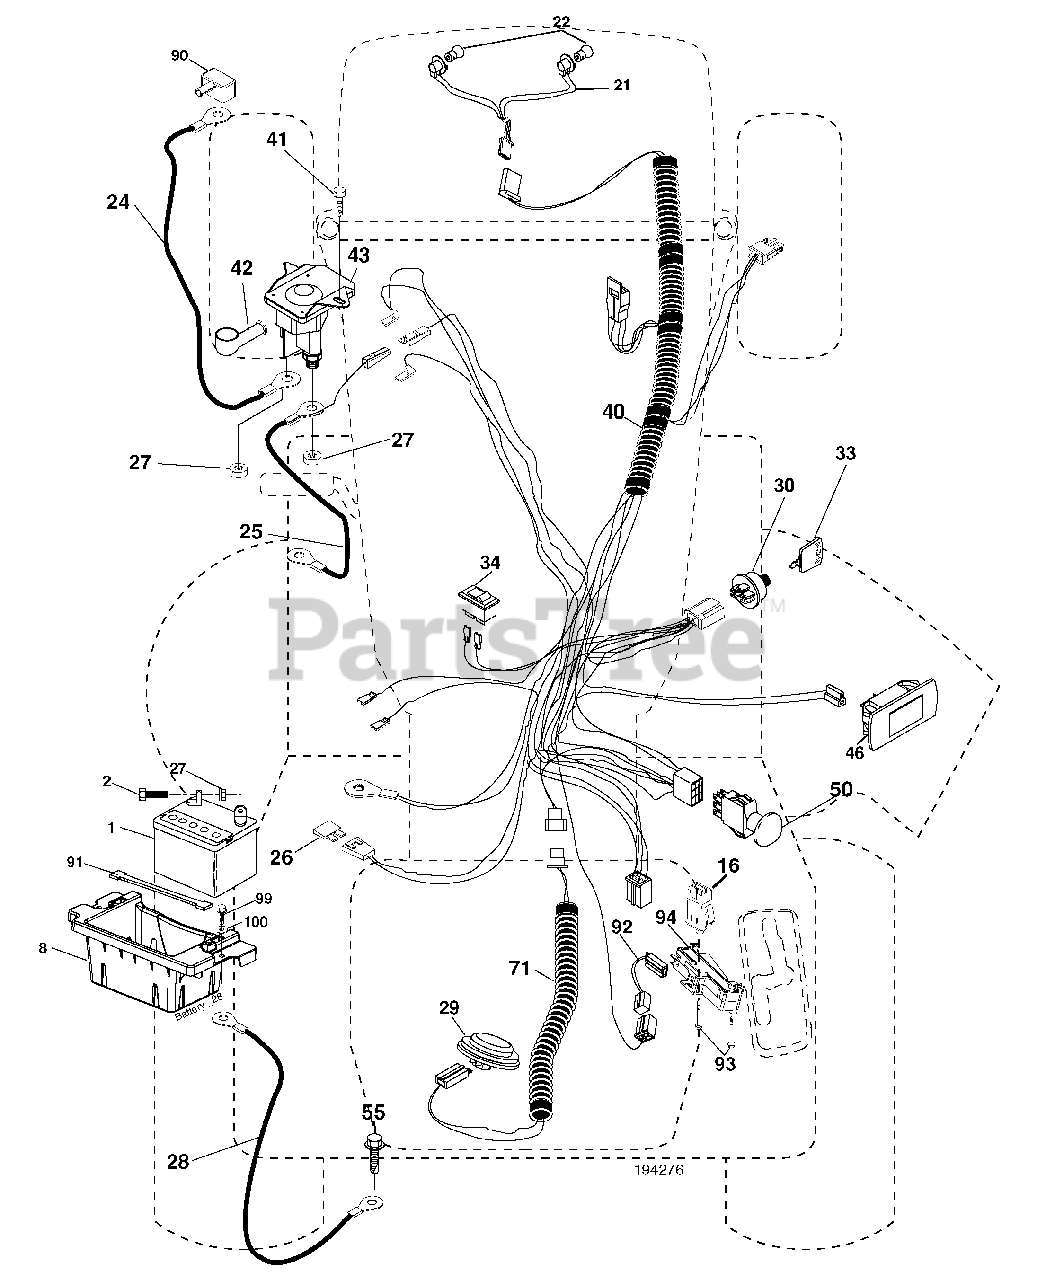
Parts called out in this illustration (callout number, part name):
1	Battery
2	Bolt Hex Head 1/4-20 x 3/4
8	Box Battery
16	Switch Interlock Push-In
21	Harness Socket Light W/4152J
22	Bulb Light
24	Cable Battery
25	Cable Starter
26	Fuse
27	Nut Keps Hex 1/4-20 unc
28	Cable, Ground
29	Switch, Seat
30	Switch, Ign
33	Key, Ignition
34	Switch Light / Reset
40	Harness Ign.
41	Screw Thd Cut 1/4-20 x 1/2
42	Cover, Terminal
43	Solenoid
46	Gauge Hourmeter
50	Switch PTO
55	Screw Thdrol 5/16-18 x 3/4 TYTT
71	Harness Ign. Dash
90	Cover Terminal Battery
91	Strap Battery Mount Front
92	Harness Pigtail
93	Screw Plastite 10-14 x 2.0
94	Module Reverse ROS
99	Screw Hexwsh Thdrol 1/4-20 x 3/4
100	Washer 9/32 x 7/8 x 16 Ga.
